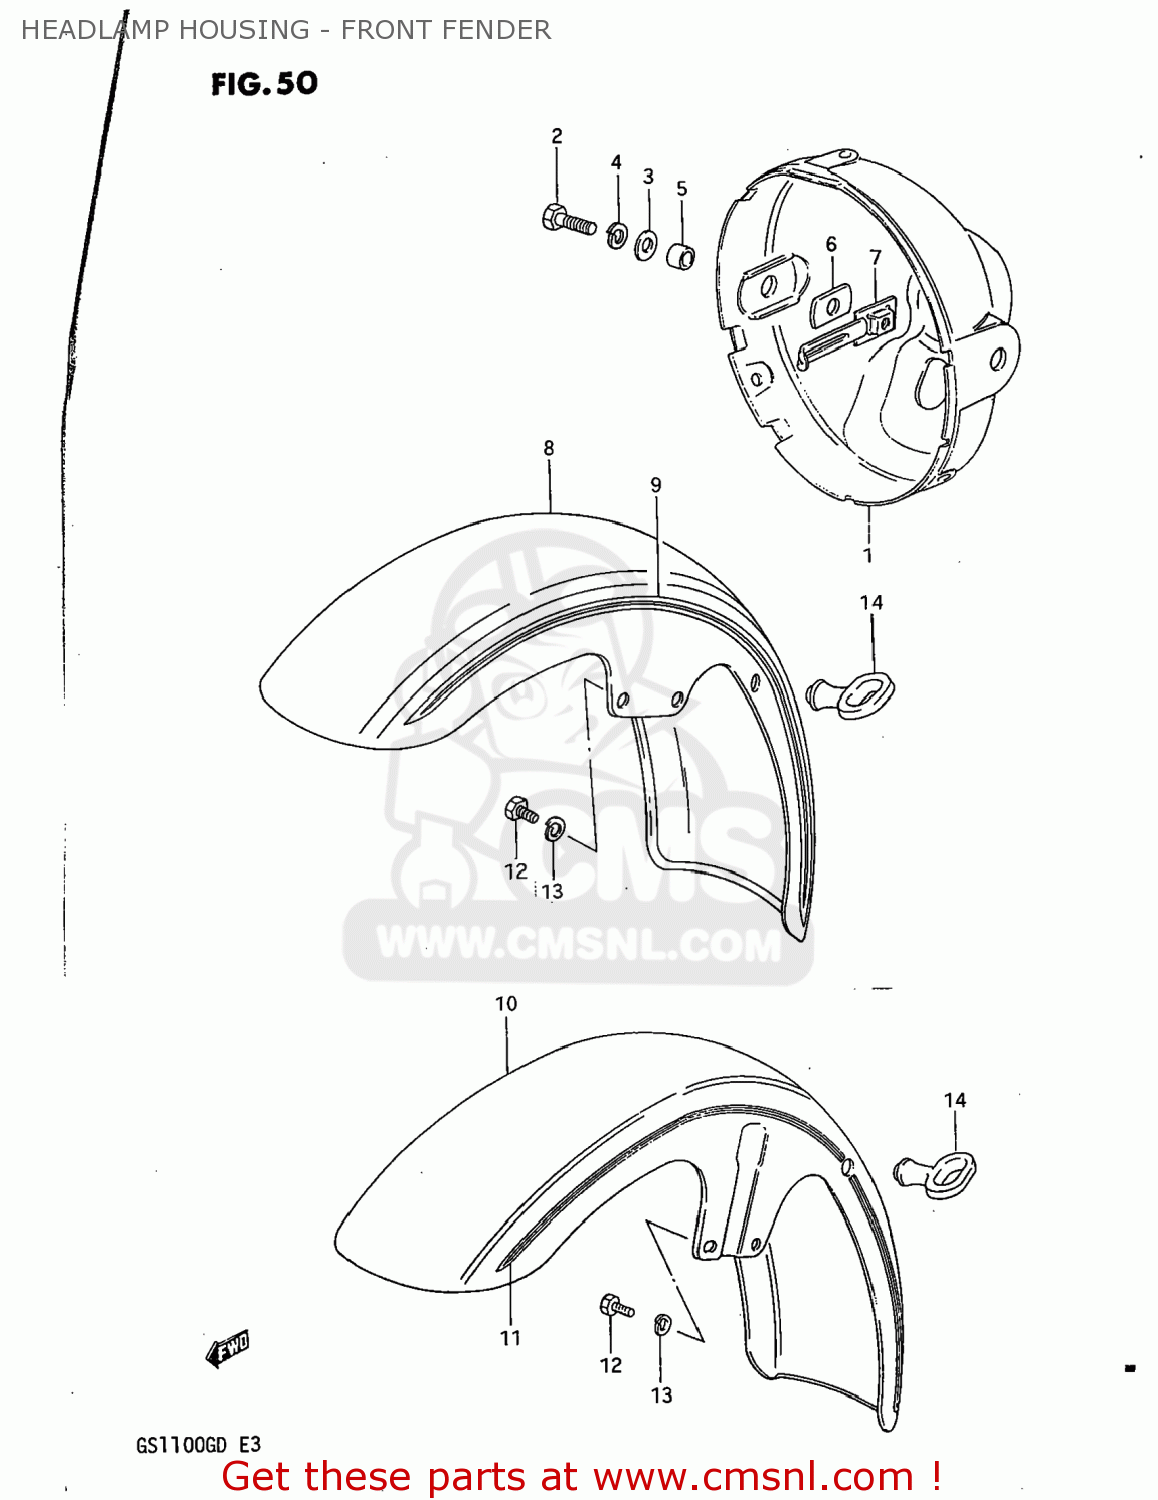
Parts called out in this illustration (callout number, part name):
1	HOUSING,HEADLAMP
2	BOLT
3	WASHER
4	LOCK WASHER
5	SPACER (8.8X12X7)
6	CUSHION
7	PLATE,HEADLAMP HOUSING
8	FENDER,FRONT
9	TAPE,FRONT FENDER
10	FENDER,FRONT
11	TAPE,FRONT FENDER
12	BOLT
13	LOCK WASHER
14	GUIDE,CABLE
